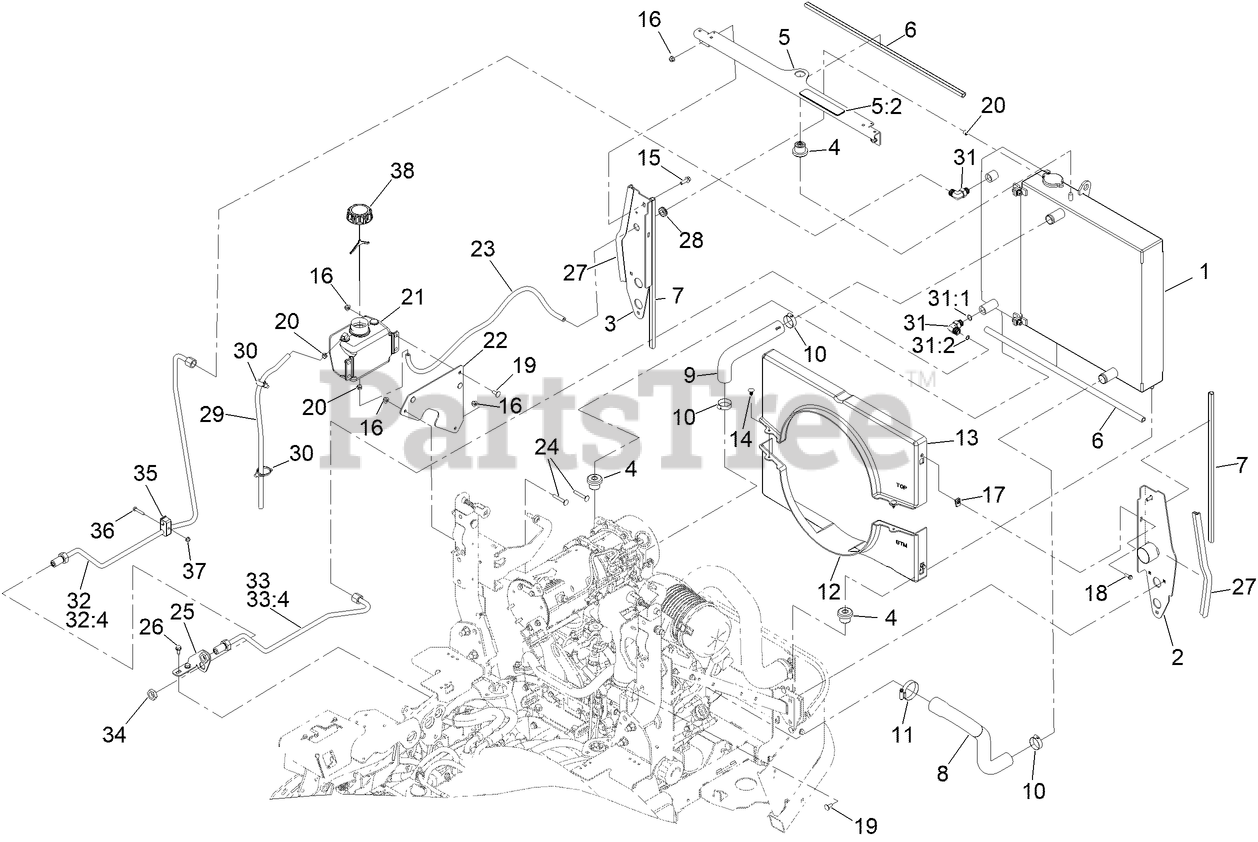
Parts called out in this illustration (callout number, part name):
1	COOLING ASM
2	SUPPORT-RADIATOR, LH
3	SUPPORT-RADIATOR, RH
4	MOUNT-ISOLATOR
5	BRACKET-TOP COOLING
5:2	DECAL-WARNING
6	SEAL-BULB
7	SEAL-BULB
8	HOSE-RADIATOR, LOWER
9	HOSE-RADIATOR, UPPER
10	CLAMP-HOSE
11	CLAMP-HOSE
12	SHROUD-BOTTOM
13	SHROUD-TOP
14	PLUG-PLASTIC
15	SCREW-HHF
16	NUT-HF, NI
18	SCREW-HWH
19	SCREW-CARR
20	CLAMP-HOSE
21	TANK-OVERFLOW, W/CAP
22	BRACKET-BOTTLE
23	HOSE-FUEL
24	BOLT-CARR
25	BRACKET-BULKHEAD
26	SCREW-HWHTF
27	SEAL-BULB
28	GROMMET
29	HOSE-FUEL
30	CLIP-TIE
31	FITTING-ELBOW, 90 DEG
31:1	O-RING
31:2	O-RING
32	HYDRAULIC TUBE ASM
32:4	O-RING
33	HYDRAULIC TUBE ASM
33:4	O-RING
34	NUT-BULKHEAD
35	CLAMP-TWIN
36	SCREW-HH
37	NUT-HF
38	CAP-W/TETHER
